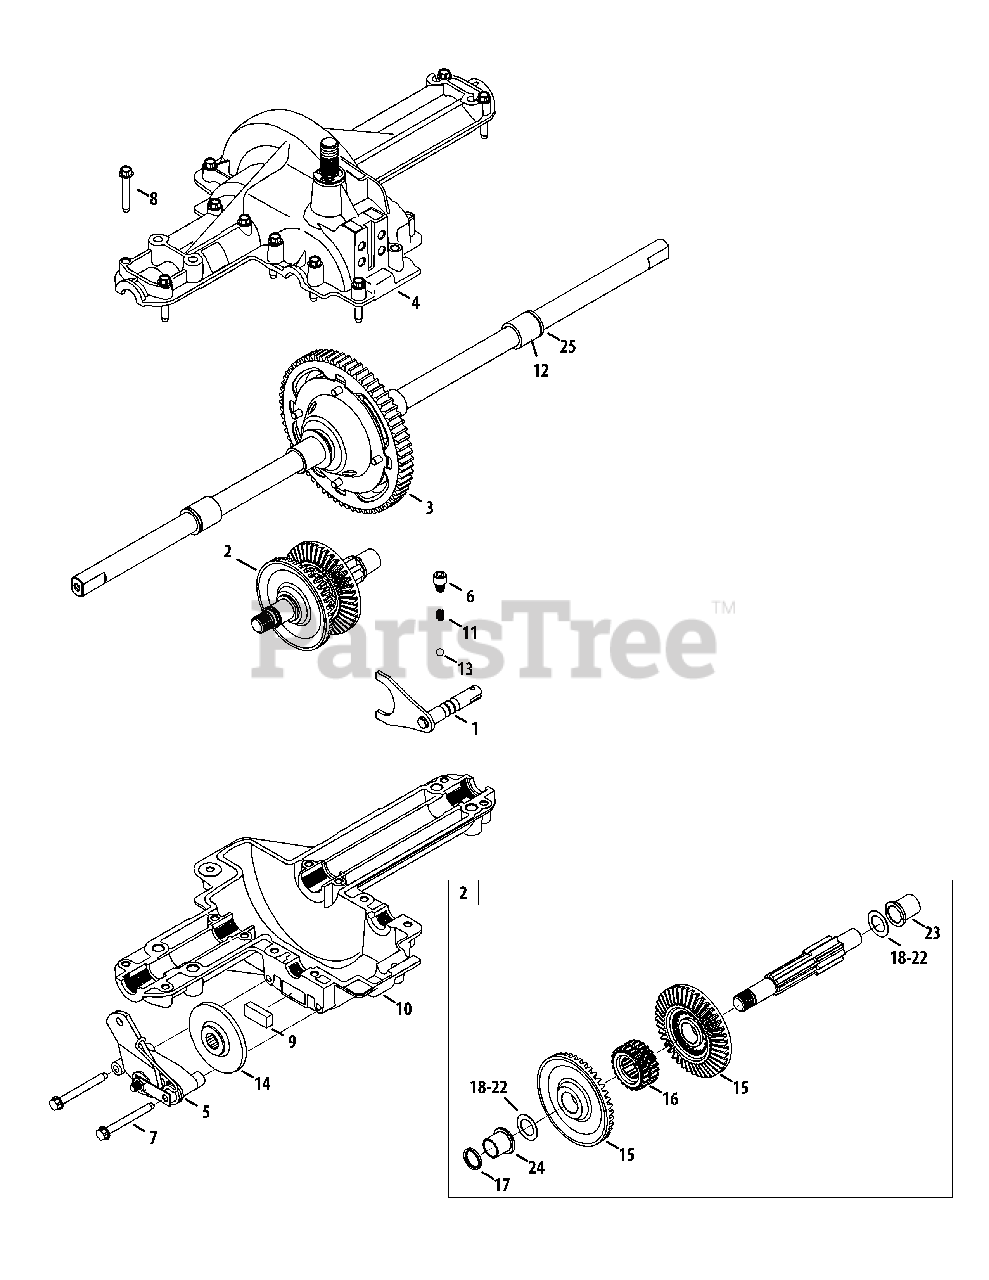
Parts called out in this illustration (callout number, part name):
1	Shaft Ass’y, Detent
2	Shaft Ass’y, Drive, Fwd-Rev
3	Differential Ass’y
4	Housing Ass’y, Upper
5	Brake Ass’y, Yoke, RH
6	Shcs, Self-tapping, 5/16-18, .375
7	Screw, Self-tapping, 1/4-20, 2.375,
8	Screw, Self-tapping, 1/4-20, 1.625,
9	Pad, Brake
10	Housing, Lower
11	Compression Spring
12	Bearing, Sleeve, .75 x 1.00 x .42
13	Ball, Detent, .250
14	Disc, Brake
15	Gear, Bevel, 42t, Spline
16	Collar, Clutch
17	Seal, .625 x .812 x .094
18	Washer, Flat, 5/8x1.00x.030 Hd
18	Washer, Flat, .634x1.00x.04
18	Washer, Flat, .63 x 1.00 x .02
18	Washer, Flat, .632x1.00x.035
22	Washer, Thrust, 1.00 x .632 x .020
23	Bearing, Flange, 5/8 x 3/4 x 3/4
24	Bearing, Flange, 5/8 x 3/4 x 15/16
25	Seal, .75 x 1.00 x .125
